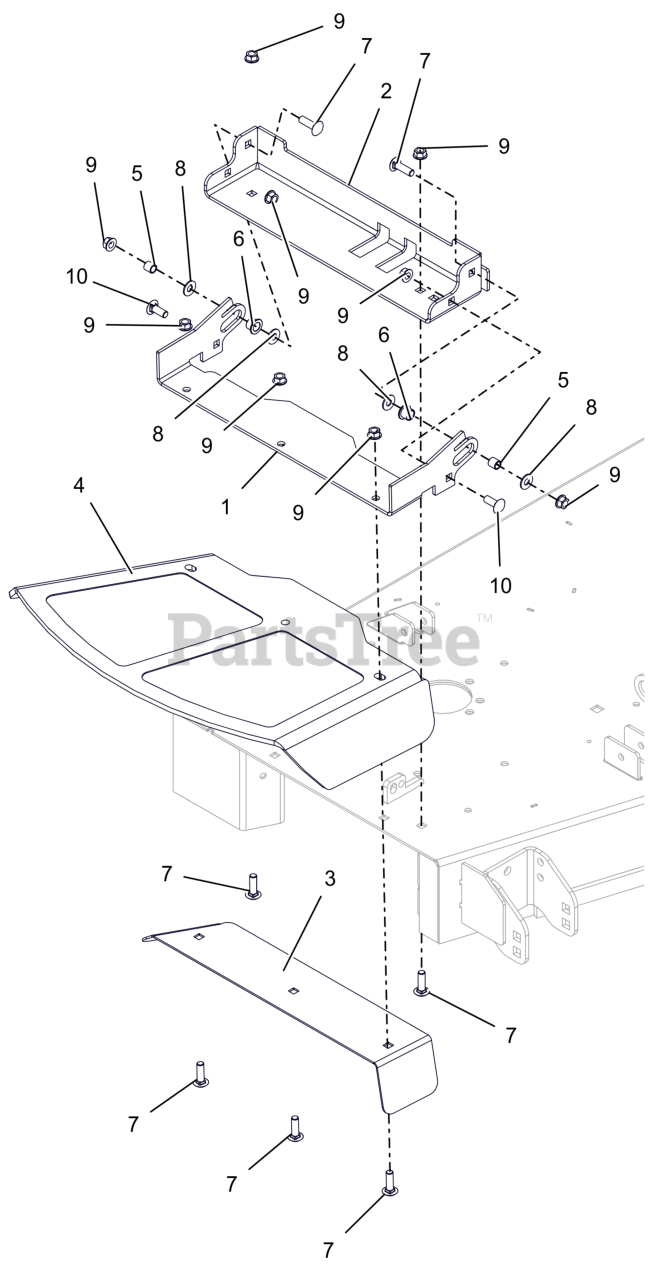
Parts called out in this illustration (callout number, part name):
1	BRKT, CHUTE MOUNT (ORANGE)
2	BASE, DISCHARGE CHUTE MTG BRKT (ORANGE)
3	PLT, DISCH. CHUTE CLMP-CE
4	CHUTE, FORMED RUBBER DISCHARGE
5	SPCR, .385X.500X.350
6	BSHG, FLANGED .50X.625X.50X.062
7	BLT,RHSSN .38-16X1.25 G5 ZCC
8	WSHR, HDND .375X.875X.064 ZCC
9	NUT-LK-CTR-FLG .375-16 GF ZCC
10	BLT,RHSSN .38-16X1.00 G5 ZCC
